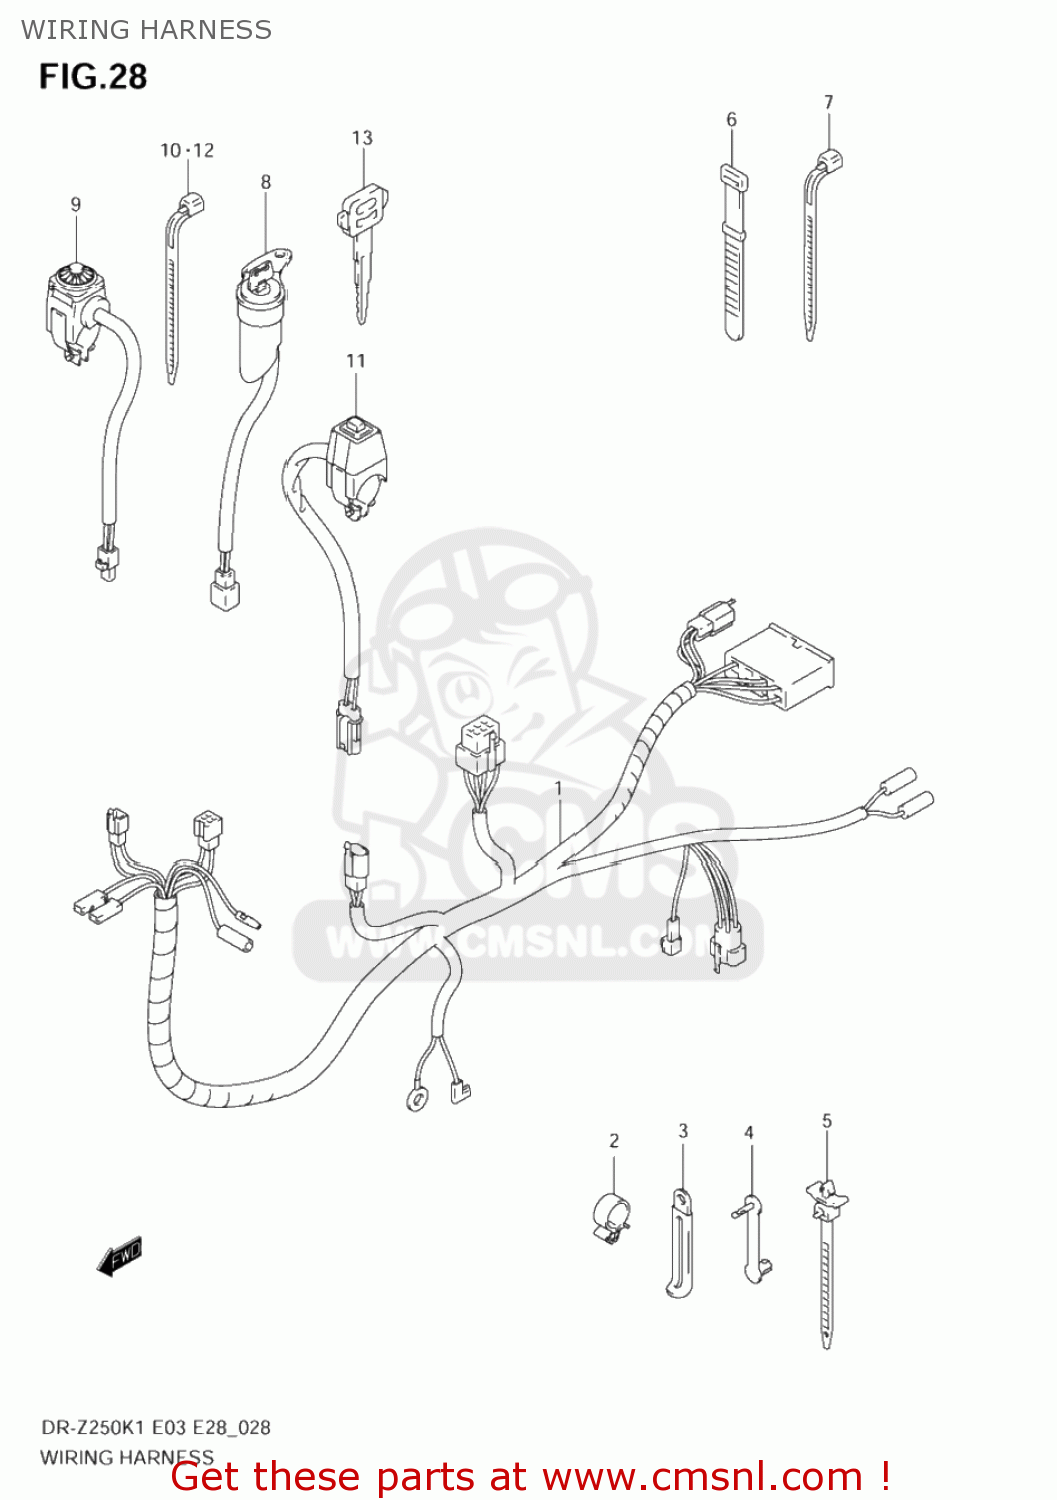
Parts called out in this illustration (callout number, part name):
1	HARNESS,WIRING
2	CLAMP
3	CLAMP(L:45)
4	CLAMP(L:33)
5	CLAMP(L:90)
6	CLAMP(L:120)
7	CLAMP(L:125)
8	SWITCH ASSY,IGNITION
9	SWITCH ASSY,STARTER
10	CLAMP(L:120)
11	SWITCH ASSY,ENGINE STOP
12	CLAMP(L:120)
13	KEY,BLANK(TYPE:C)
